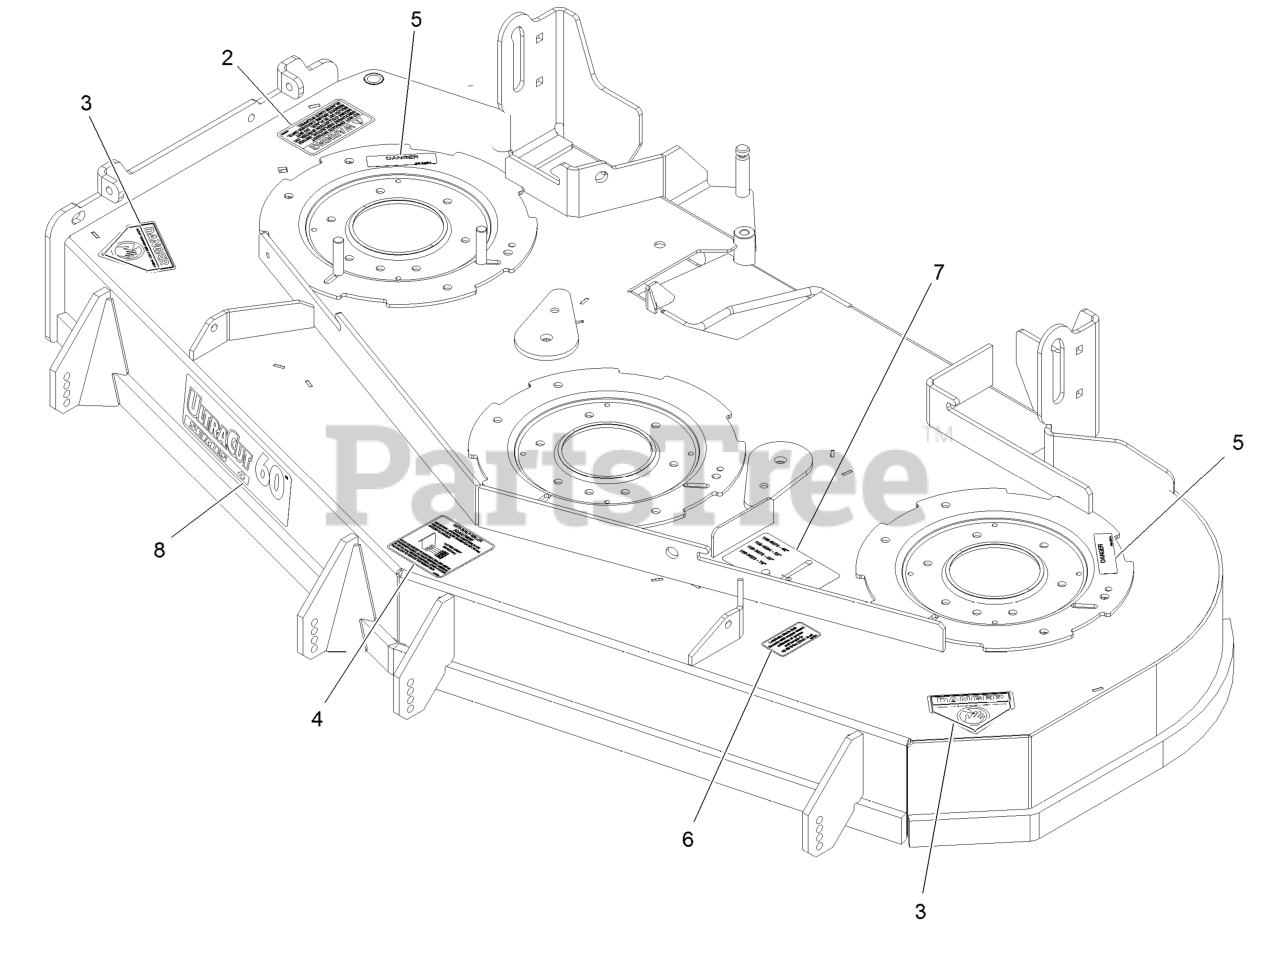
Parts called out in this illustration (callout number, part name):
2	DECAL-WARNING, DISCHARGE
3	DECAL-DANGER
4	DECAL,ANTISCALP
5	DECAL-COVER, MISSING
6	DECAL,BOLT TORQUE
7	DECAL,BELT ROUTING
8	DECAL,ULTRACUT 60 SERIES
